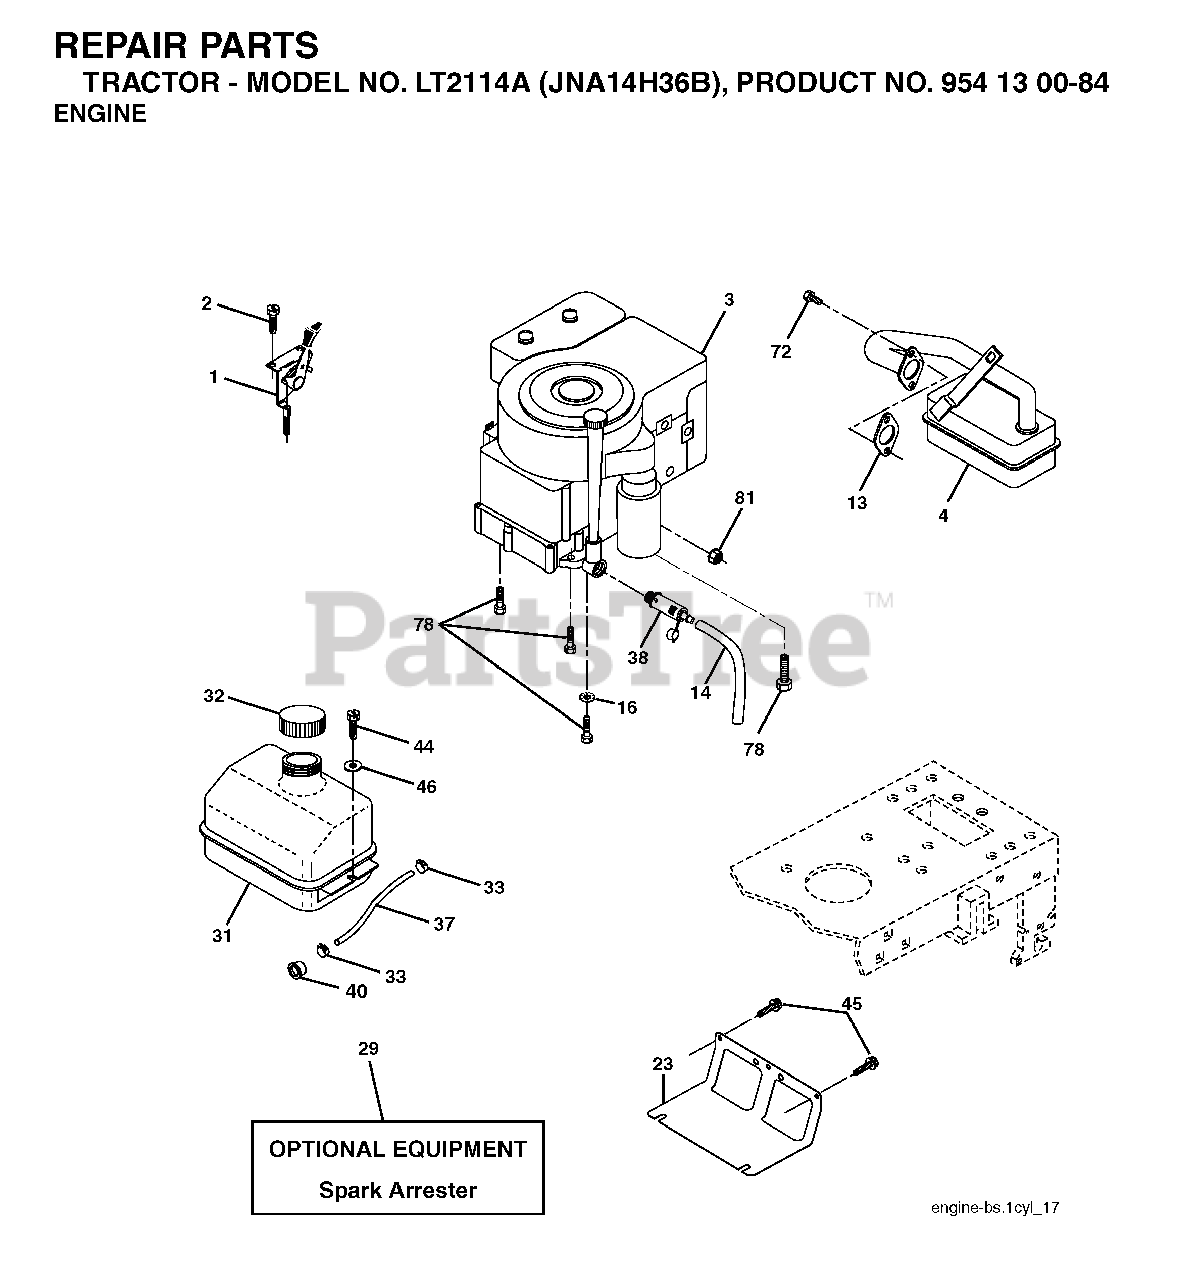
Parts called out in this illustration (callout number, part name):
1	CONTROL TH/CH FLAG
2	SCREW
13	REPL BY 532 27 22-93
14	TUBE, DRAIN OIL ASM.
16	LOCKWASHER
23	SHEILD.BROWNING.DBR.GUARD
29	ARRESTER SPARK (OPTIONAL)
31	TANK FUEL FRONT
32	FUEL CAP
33	HOSE CLAMP
37	LINE.FUEL.20
38	PLUG DRAIN OIL EASY
40	GROMMET T
44	SCREW HEXWSHR 1/4-20X3/4
45	SCREW, 3/8-16X3/4
72	SCREW.SOCKET.HEAD.5/16-18
78	SCREW.3/8-16
81	NUT
